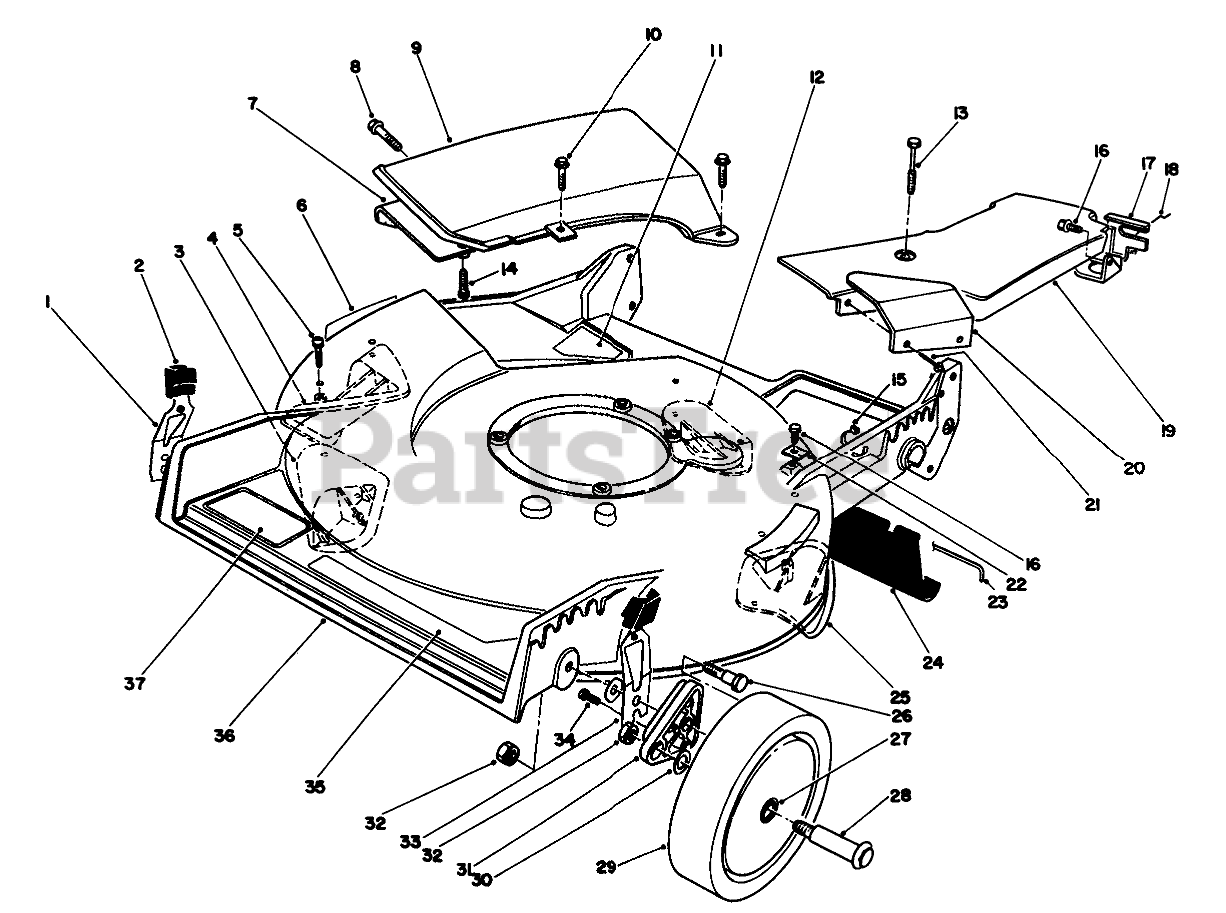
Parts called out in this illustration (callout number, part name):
1	RH SPRING ARM ASSEMBLY
2	KNOB-ARM
3	KICKER
4	KICKER
5	#8 X .625" PHILPS PAN H
6	DECAL-DANGER
7	Deflector-Recycler
8	SCREW AND WASHER ASM
9	Cover Assembly (Incl. Ref. #7 & 14)
10	SCREW-HWH
11	DECAL - DANGER
12	KICKER
13	SCREW-HHFTF
15	TIE-CABLE
16	SCREW-HWHTF
17	Bracket-Adj. Trac
18	RETAINER-CABLE
19	Belt Cover Assembly (Incl. Ref. #20 & 21)
20	HEAT SHIELD
21	RIVET-HEAD, FLAT
22	CLAMP-CABLE
23	ROD-SHIELD
24	SHIELD-TRAILING
25	KICKER
26	SCREW-SHOULDER
27	BUSHING
28	WHEEL BOLT
29	Wheel & Tire Assembly (Incl. Ref. #27)
30	WASHER
31	ARM-PIVOT, FRONT
32	Nut
33	LH SPRING ARM ASSEMBLY
34	SCREW-HWH
35	DECAL - DECK
36	Housing Assembly (Incl. Ref. #3-6, 12, & 25)
37	DECAL
